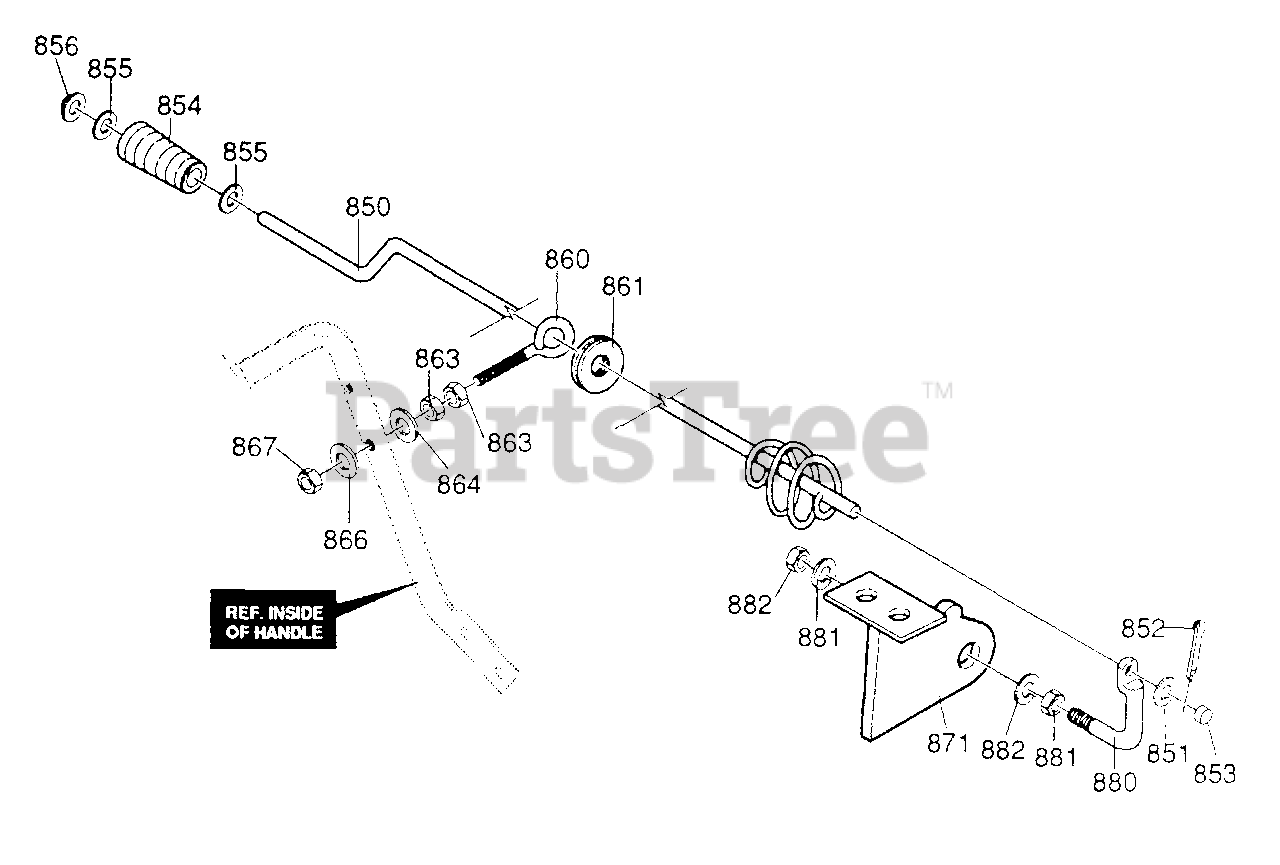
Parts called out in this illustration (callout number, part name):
850	CRANK, ASSY CHUTE
851	FLATWASHER, .406 x .81 x .065
852	PIN, COTTER .094 DIA x 1.00 LONG
853	CAP, PLASTIC, 3/8 ID
854	KNOB, SLEEVE
855	FLATWASHER, .406 x .81 x .065
856	NUT, PUSH ON 3/8"
860	BOLT, EYE 3/8-16 x 5.00 .63 ID
861	GROMMET, EYE BOLT .40 ID x .435WD
863	NUT, 3/8-16 HEXJAM
864	FLATWASHER, .406 x .81 x.065
866	FLATWASHER, .406 x .81 x.065
867	NUT, 3/8-16 HEXNYL
871	PLATE, ASSY MTG STL CHUTE
880	ROD, CHUTE CONT 420T
881	NUT, 1/2-20 HXJAM
882	WASHER, REGSPTLK .523 x .87 x .14
